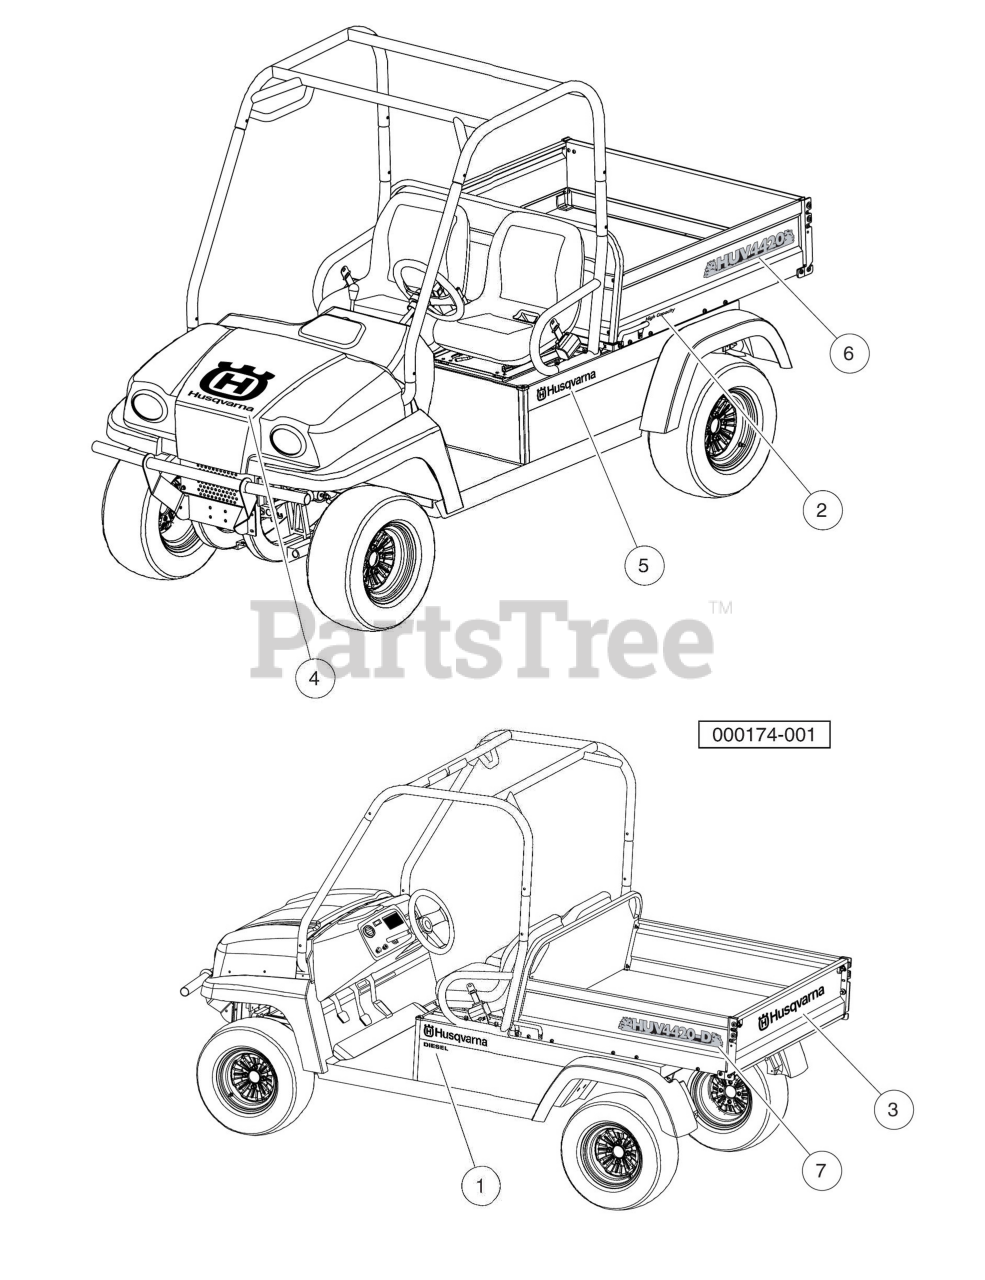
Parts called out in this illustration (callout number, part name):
1	Decal, Diesel
2	Decal, High-Capacity
3	Decal, Husqvarna, Tailgate
4	Decal, Husqvarna Cowl
5	Decal, Husqvarna, Side Panel
6	Decal, Bed
7	Decal, Bed
